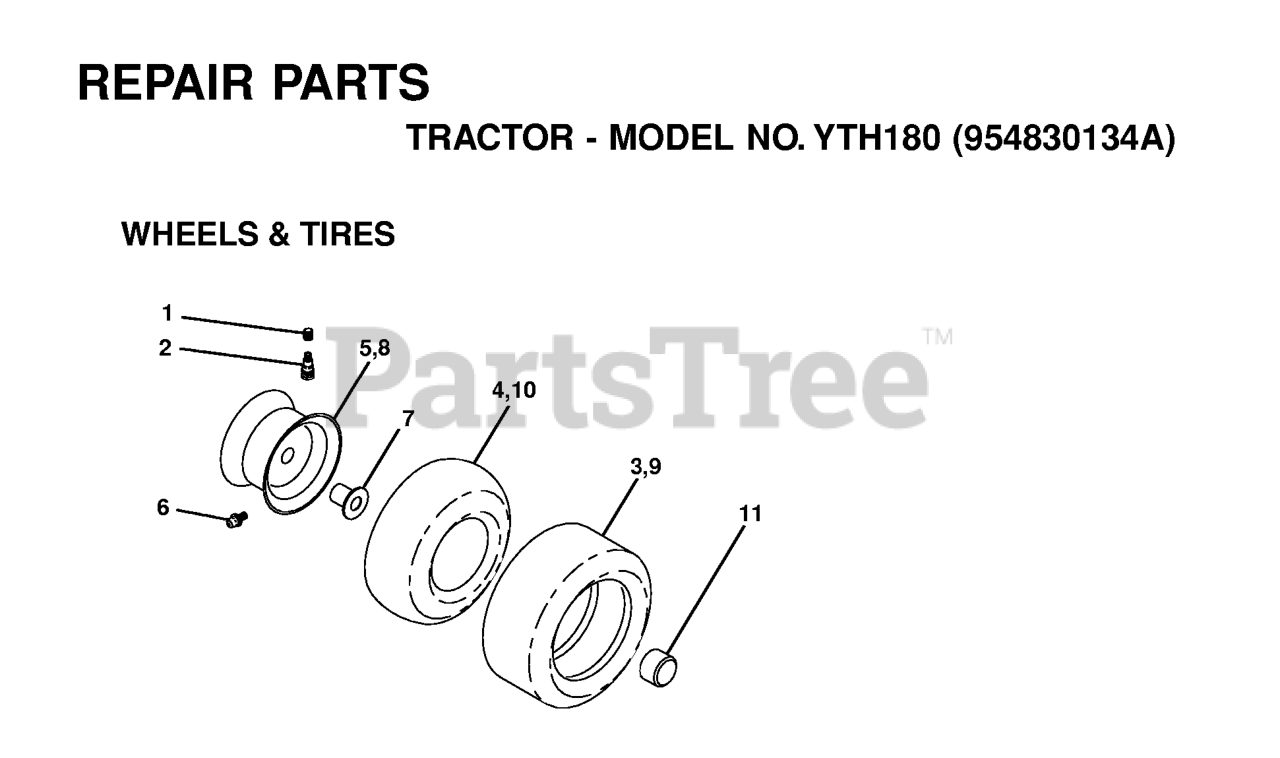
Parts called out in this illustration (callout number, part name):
2	VALVE STEM LT
3	TIRE HEAVY DUTY
4	TUBE.5.3/4.5/6
5	RIM ASM 6" FRONT SILVER
6	FITTING LT
7	BEARING T
8	RIM ASM 8" REAR SILVER
9	TIRE.TS.20X10-8
10	TUBE
11	CAP.HUB.FRONT.LT.BLACK
